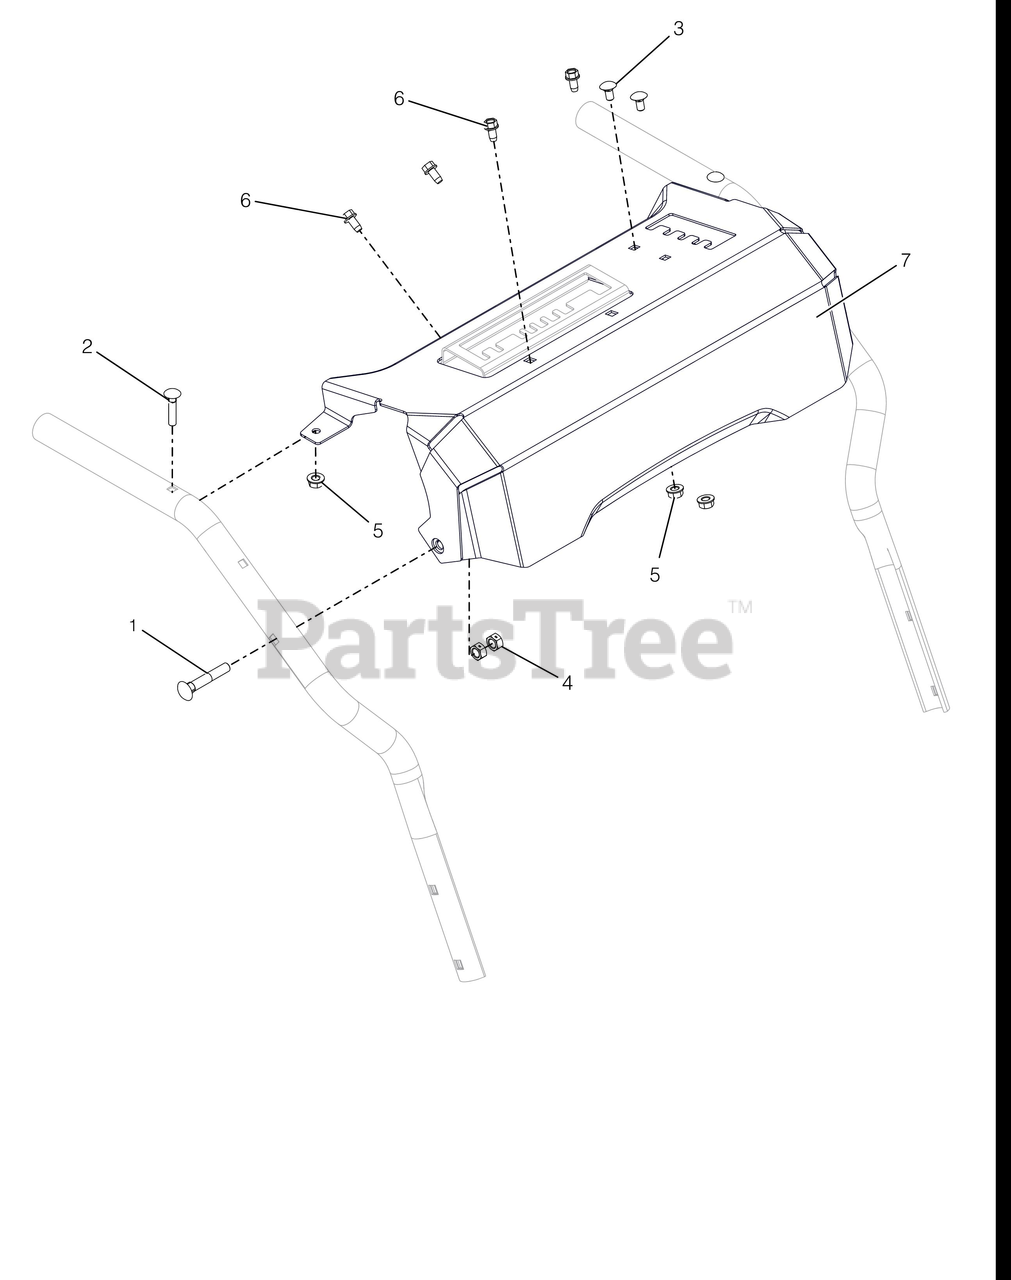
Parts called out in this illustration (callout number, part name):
1	BLT-RDHDXLSQNK .31-18X2.0 G5YZ
2	BLT-RDHDXLSQNK.25-20X1.25 G5ZC
3	@BLT-RDHDSQNK .25-20X.50 G5YZ
4	@NUT-LK-CTR .31-18 YWZC
5	@NUT-LK-TOP-FLG .25-20 YWZC
6	SCR-TAP .25-20X.50 HWH TR YWZ
7	CTRL PANEL W/DECAL-SNOTEK MANU
